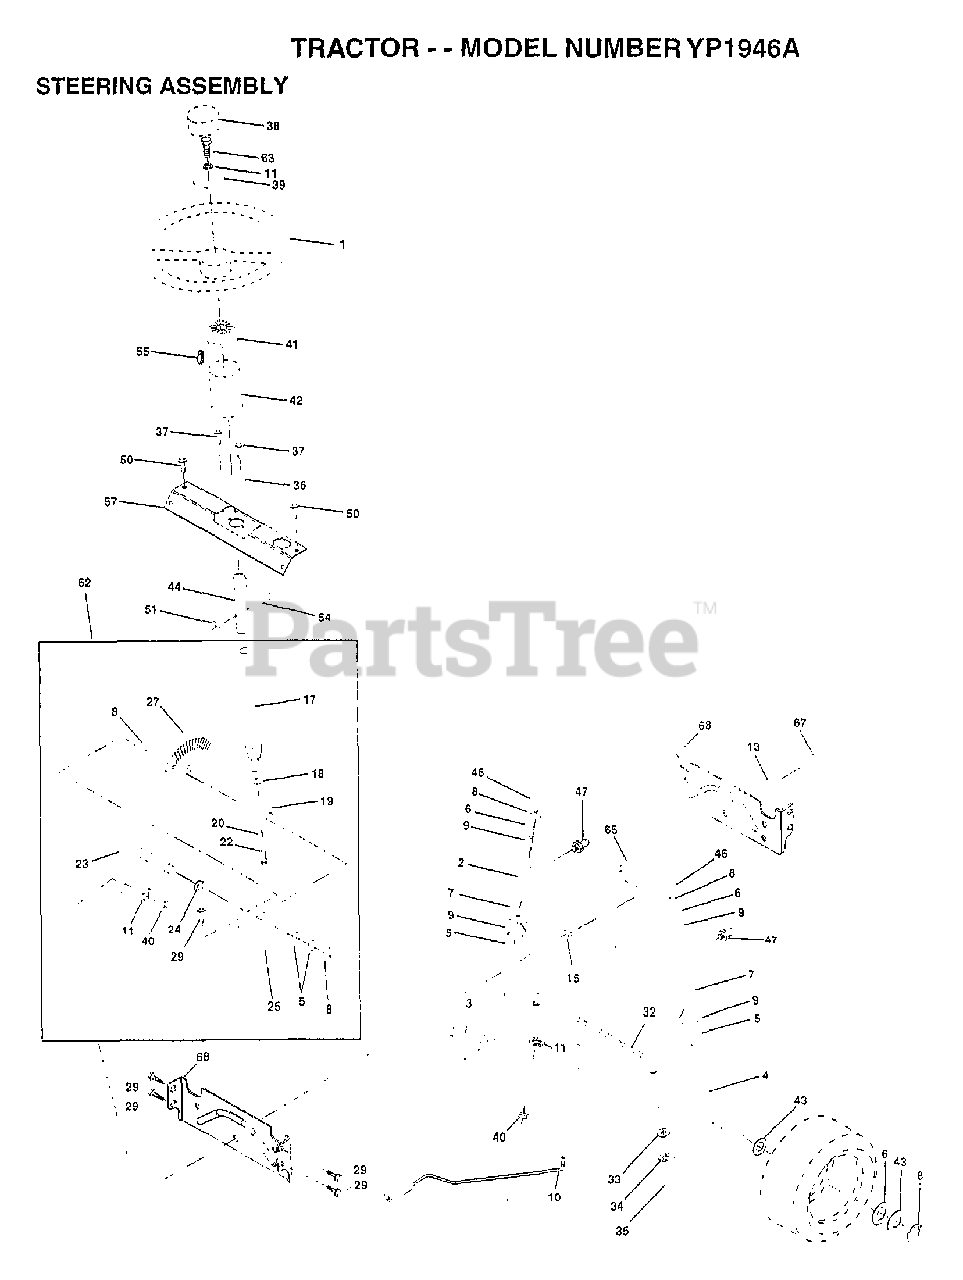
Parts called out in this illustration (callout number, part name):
2	AXLE ASM
3	SPINDLE.ASM.LH
4	"SPINDLE ASM,RH"
5	WASHER .T
6	WASHER
7	WASHER
8	RING
10	DRAGLINK-STAMPED
11	LOCKWASHER
13	BEARING AXLE
15	"NUT-LOC,FLANGE LT"
17	SHAFT ASM STEERIN
18	THRUST WASHER
19	SUPPORT.SHAFT
22	SCREW HEX SOC1/4-
25	BRKT-STEERING
27	GEAR SECTOR
29	SCREW
32	ROD.TIE.19.75
33	WASHER M
34	LOCKWASHER
35	NUT.LOCK.5/16-24
36	BUSHING.STR.623
37	"SCREW-TT,10-32 FL"
38	"INSERT,STR WHEEL"
39	WASHER T
40	GRIPCO NUT
41	ADAPTER LT
42	BOOT SHAFT STEER
43	WASHER
44	SHAFT EXT STEERIN
46	CAP
47	ZERK M
50	SCREW HEX CRT
51	NUT
54	BOLT
55	CLIP TINNERMAN
57	SUPPORT SHAFT STR
62	KIT STEERING ASM
63	BOLT
65	SPACER AXLE
66	"BEARING-ARM,PITMA"
67	BOLT
68	BRACE AXLE
